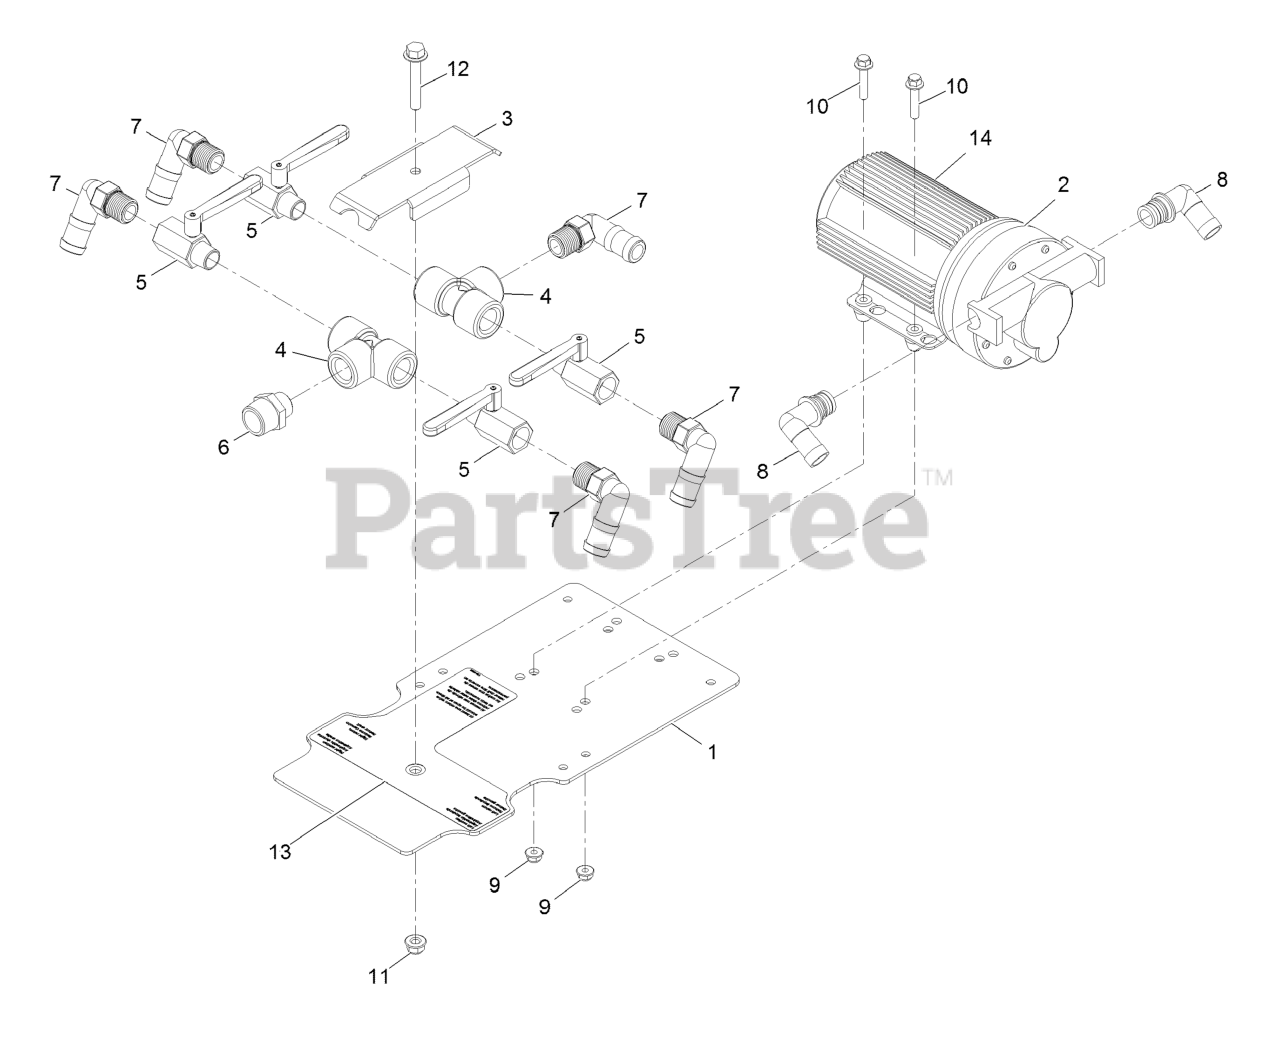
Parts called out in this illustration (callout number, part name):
1	MOUNT-PLATE, LIQUID VALVE
2	PUMP-5.3 GPM
3	PLATE-CLAMP, LIQUID VALVE
5	VALVE-CHROME, 1/2
6	FITTING-NIPPLE
7	ELBOW-90
8	FITTING-ELBOW, 3/4QD X 3/
9	Nut-Hex Flange
10	SCREW-HHF
11	Nut-Hex Flange
12	SCREW-HHF
13	DECAL-VALVE, TANK
14	HEATSINK-3.0""
